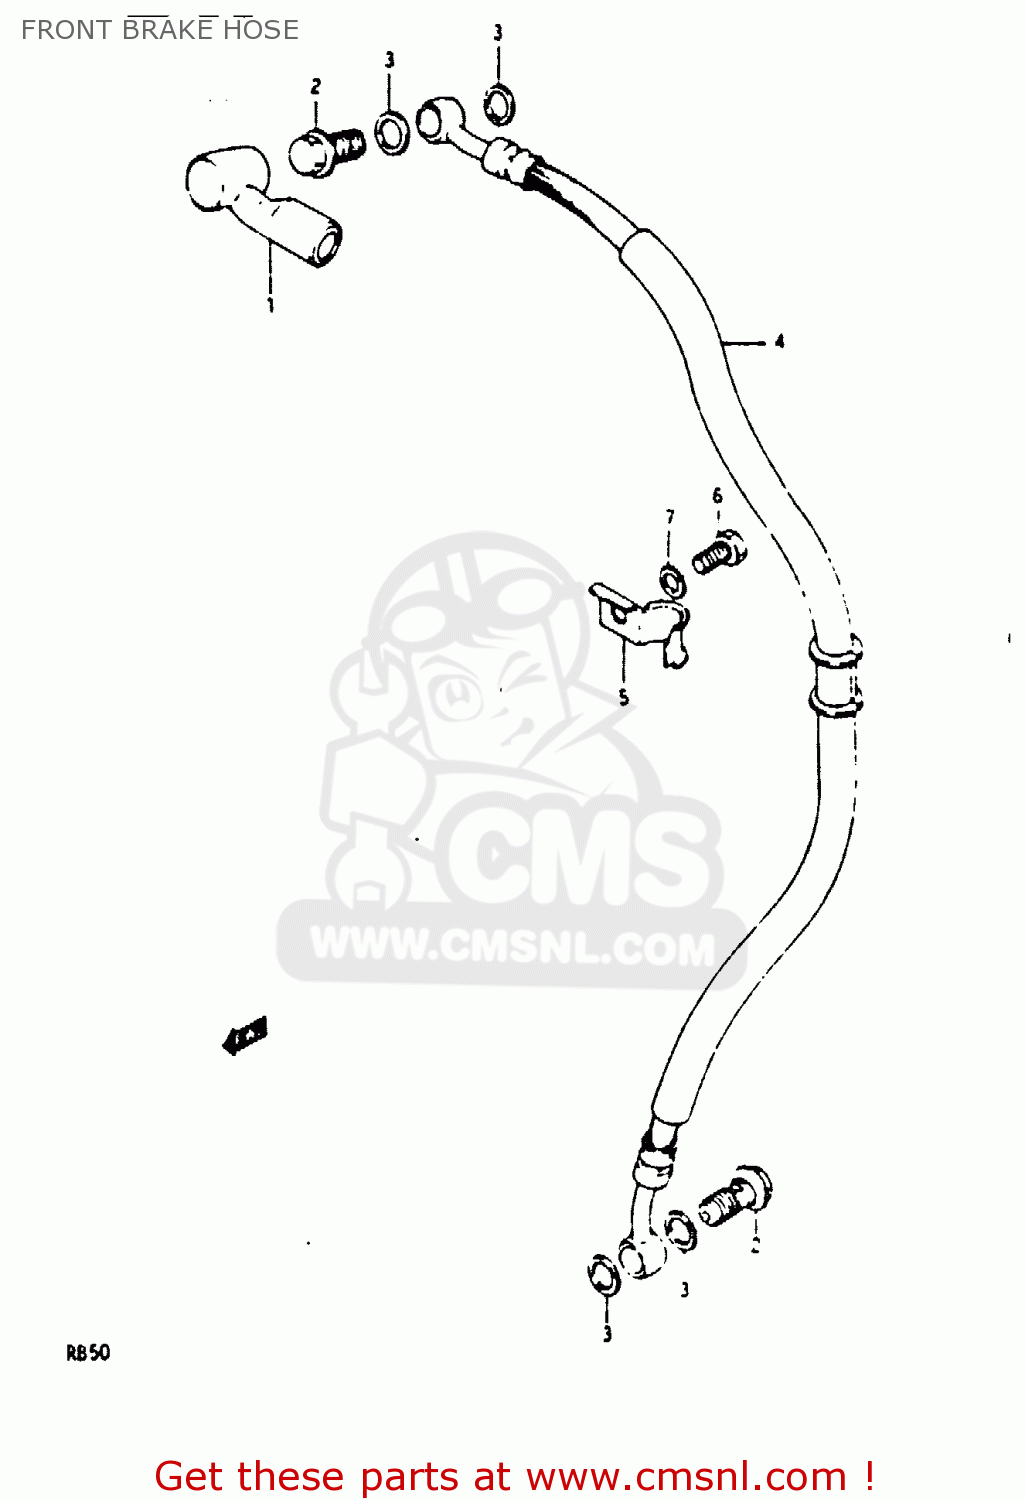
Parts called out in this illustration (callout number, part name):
1	BOOT,MASTER CYLINDER
2	BOLT UNION
3	WASHER(10X15X1.5)
4	HOSE COMP,FRONT BRAKE
5	CLAMP,BRAKE HOSE
6	BOLT
7	WASHER,LOCK
